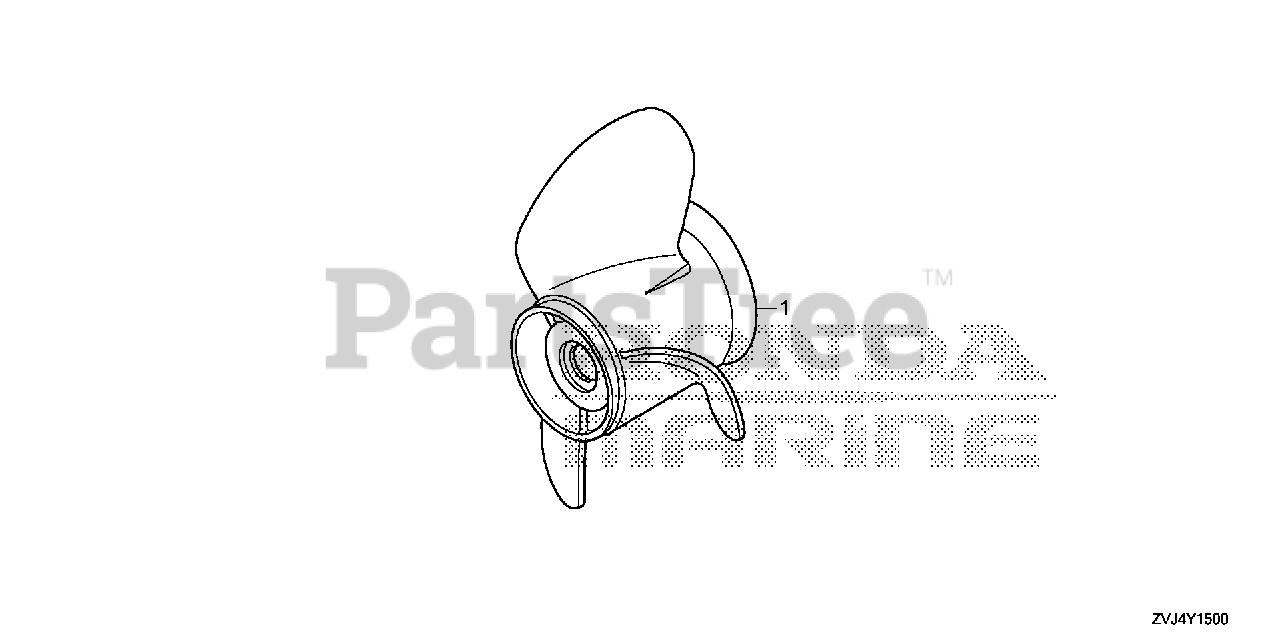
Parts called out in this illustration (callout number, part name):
1	PROPELLER, THREE-BLADE (15-3/4X15) (C/R)
1	PROPELLER, THREE-BLADE (15-1/2X17) (C/R)
1	PROPELLER, THREE-BLADE (15-1/4X19) (C/R)
1	PROPELLER, THREE-BLADE (15X21) (C/R)
1	PROPELLER, THREE-BLADE (14-3/4X23) (C/R)
1	PROPELLER, THREE-BLADE (14-1/2X25) (C/R)
1	PROPELLER, THREE-BLADE (14-1/2X27) (C/R)
